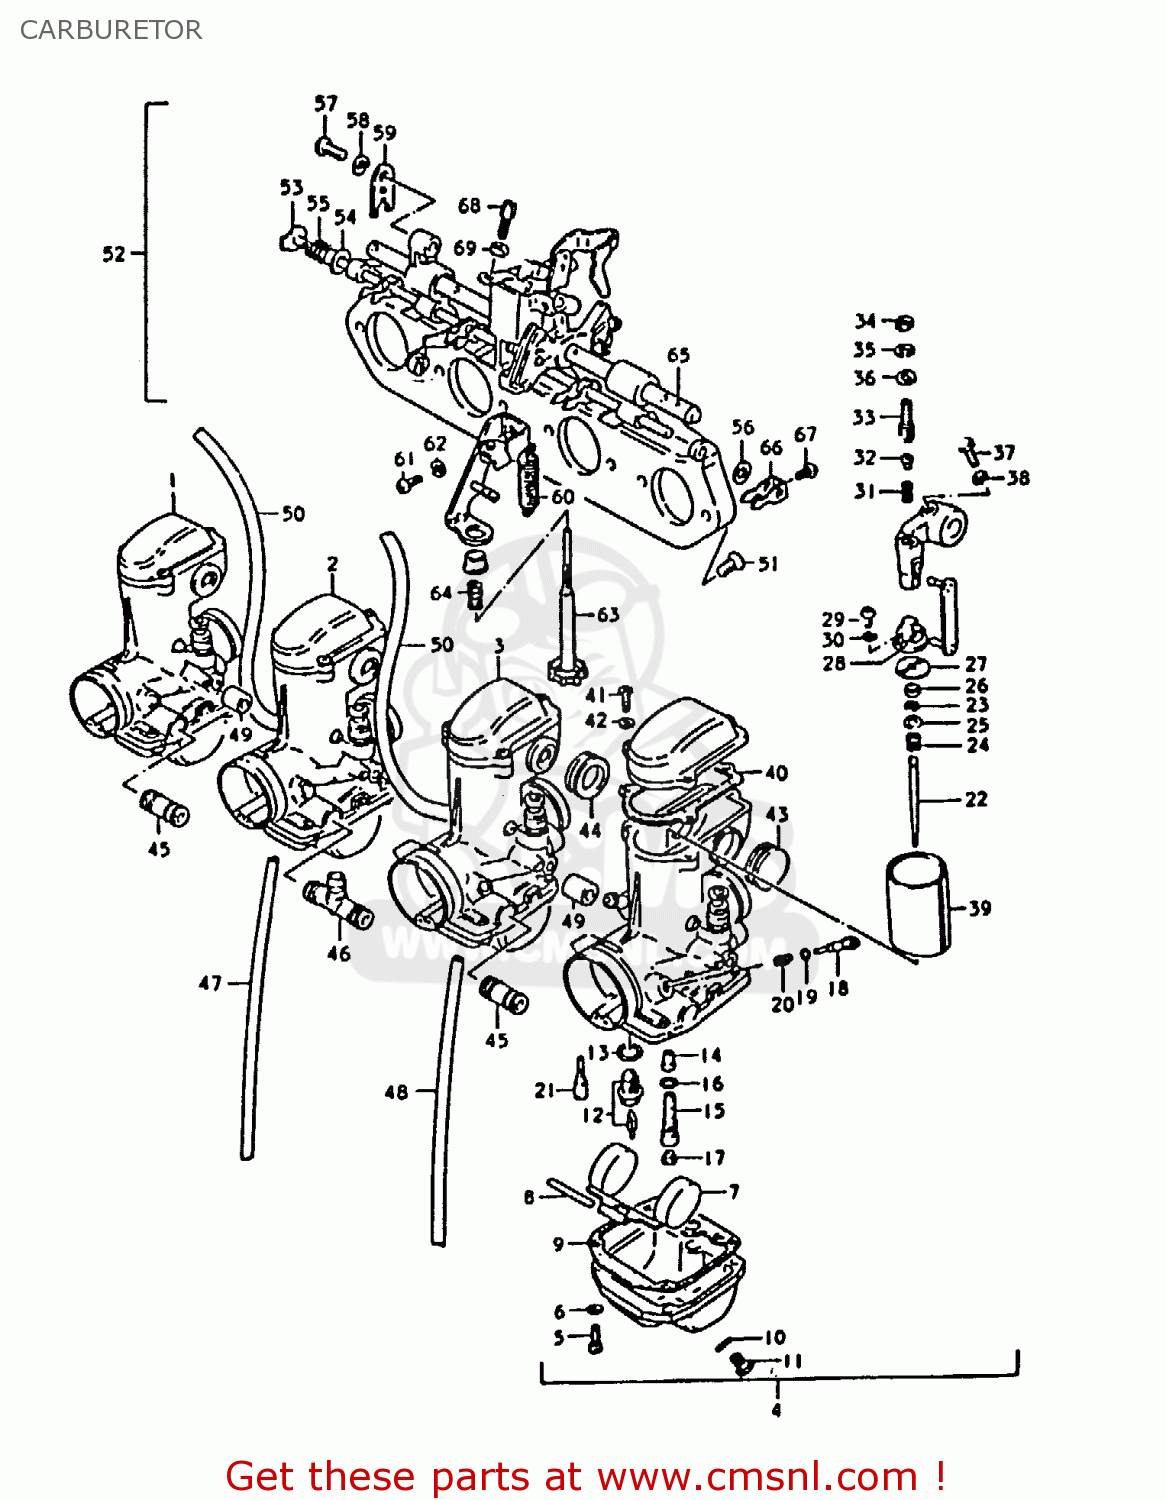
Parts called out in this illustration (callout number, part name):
1	CARBURETOR ASSY., NO.1
2	CARBURETOR ASSY, NO.2
3	CARBURETOR ASSY, NO.4
4	CARBURETOR ASSY, NO.4
5	SCREW
6	LOCK WASHER
7	FLOAT
8	PIN,FLOAT
9	GASKET,FLOAT CHAMBER (NAS)
10	O RING
11	SCREW
12	VALVE ASSEMBLY,NEEDLE
13	GASKET,VALVE SEAT (NAS)
14	JET, NEEDLE
15	PIPE,BLEEDER
16	O RING
17	JET
18	SCREW,PILOT AIR
19	O RING
20	SPRING
21	JET
22	NEEDLE,JET
23	CLIP
24	SPRING
25	WASHER,JET NEEDLE
26	RING
27	PLATE,THROTTLE VALVE
28	CONNECTOR
29	SCREW
30	LOCK WASHER
31	SPRING
32	PIN,CARBURETOR
33	SCREW
34	NUT
35	LOCK WASHER
36	WASHER
37	BOLT
38	LOCK WASHER
39	VALVE,THROTTLE
40	GASKET (NAS)
41	SCREW
42	LOCK WASHER
43	PIPE,DELIVERY
44	SEAL
45	NIPPLE
46	NIPPLE
47	HOSE
48	HOSE
49	HOSE
50	HOSE 4.5X8X390
51	SCREW
52	CARBURETOR ASSEMBLY
53	SHAFT,STARTER
54	WASHER
55	SPRING
56	WASHER,STARTER SHAFT
57	SCREW
58	LOCK WASHER
59	GASKET
60	SPRING,THROTTLE RETURN
61	SCREW
62	LOCK WASHER
63	ADJUSTER
64	SPRING,THROTTLE SCREW
65	SHAFT ASSEMBLY
66	LEVER,STARTER
67	SCREW
68	ADJUSTER,CABLE
69	NUT
